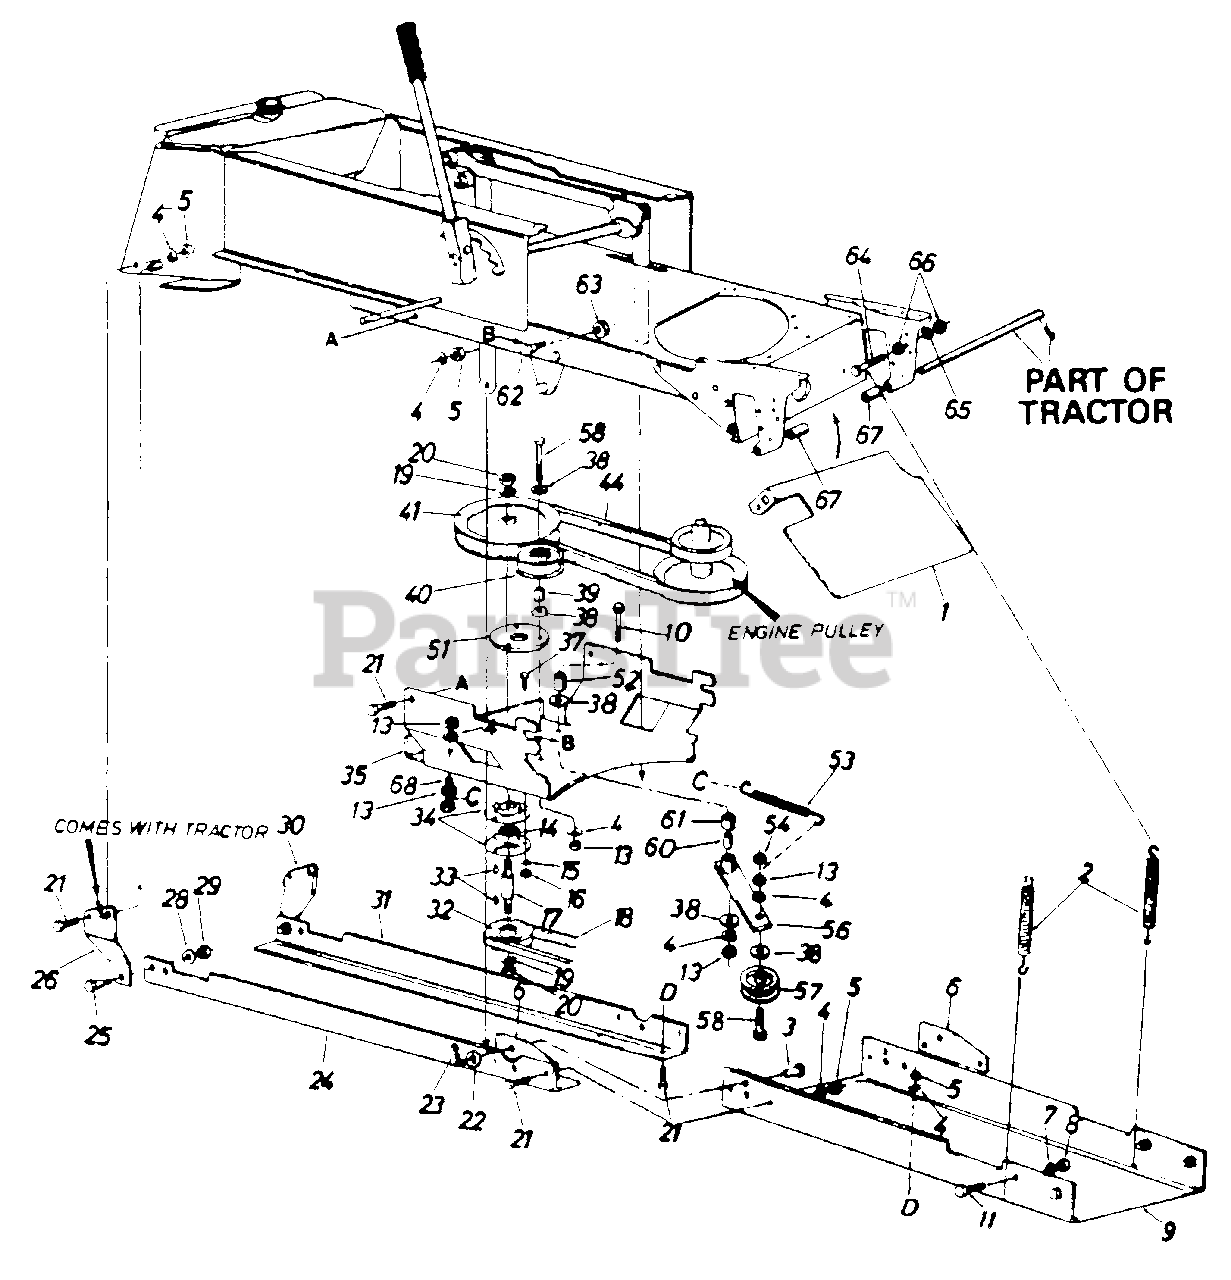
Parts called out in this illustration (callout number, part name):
3	Clevis Pin
4	L.-Wash. 3/8" I.D.
5	Hex L.-Nut 3/8-24 Thd.
6	Attaching Plate
7	L.-Wash. 1/2" I.D.
8	Hex L.-Nut 1/2-20 Thd.
11	Hex Bolt 1/2-20 x 1.25" Lg.
13	Hex J m Nut 3/8-16 Thd.
14	Ball Bearing
15	L.-Wash. 5/16" I.D
16	Hex Nut 5/16-18 Thd.
17	Spindb
18	"V"-Belt
19	L-Wash. 5/8" Nn
20	Hex Jam Nut 5/8-11 Thd.
21	Hex Bolt 3/8-24 x 1.00" Lg.
22	Flat Washer
23	Intemal Cotter Pin
29	Hex Nut 7/16-14 Thd.
33	#6 Hi-Pro Key 3/16 x 5/8" Dia.
34	Bearing Housing
35	Supporting Bracket
37	Hex Sems Bolt 5/16-18 x 1"'
38	Fl.-Wash. .38" I.D. x 1" O.D.
39	Spacer .38" I.D. x .62' O.D.
40	Fl.-Idler Pulley
41	Uppor Drive Pulley
44	"V"-Belt
53	Extcnsion Sprin5 4.75" Lg.
54	Hex Cent. L.-Nut 3/8-1B Thd.
56	Idler Arm Ass'y.
57	Idler Pulley
58	Hex Bolt 3/8-16 x 2.25" Lg.
60	Spacer .377" I.D. x .83" Lg.
61	Spacer .38" I.D. x .565" Lg.
62	Shouldor Bdt .498 Dia.
63	Hat Cent. L-Nut 3/8-16 Thd.
64	Hex Bolt 1/4-28 x 1.50" 4.
65	L-Wh. 114" I.D.
66	Hex Nut 11428 Thd.
67	Spacer .63" I.D. x 1.75" 4.
68	Hex Bolt 3/8-16 x 2" 4.
